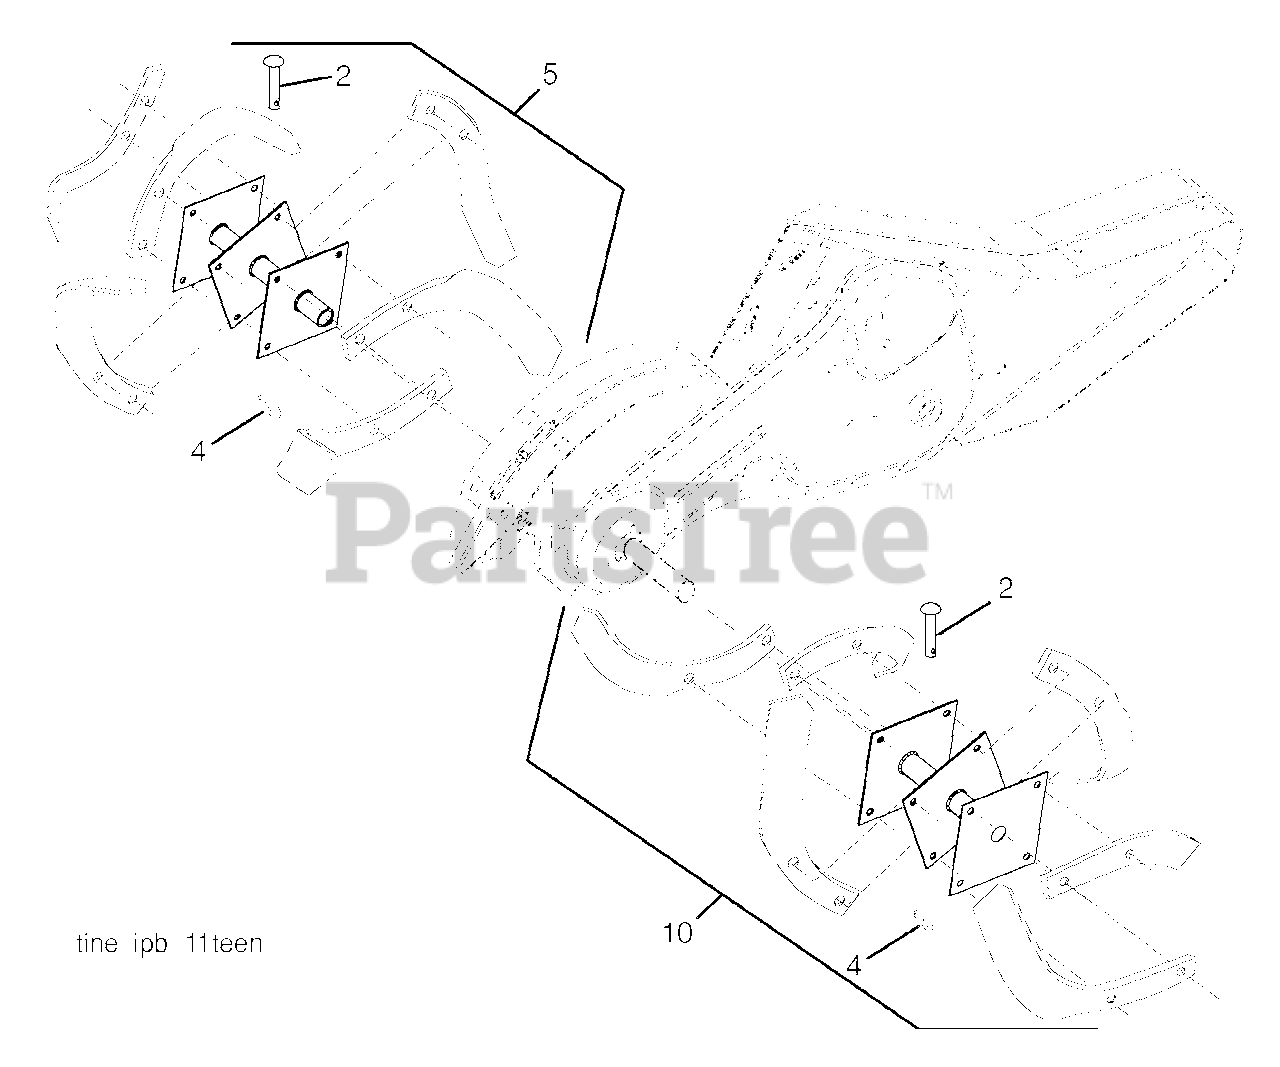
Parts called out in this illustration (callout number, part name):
2	CLEVIS PIN
4	SPRING RETAINER
5	TINE.ASM.LH.TILLER.BLACK
10	TINE.ASM.RH.PNT.479
